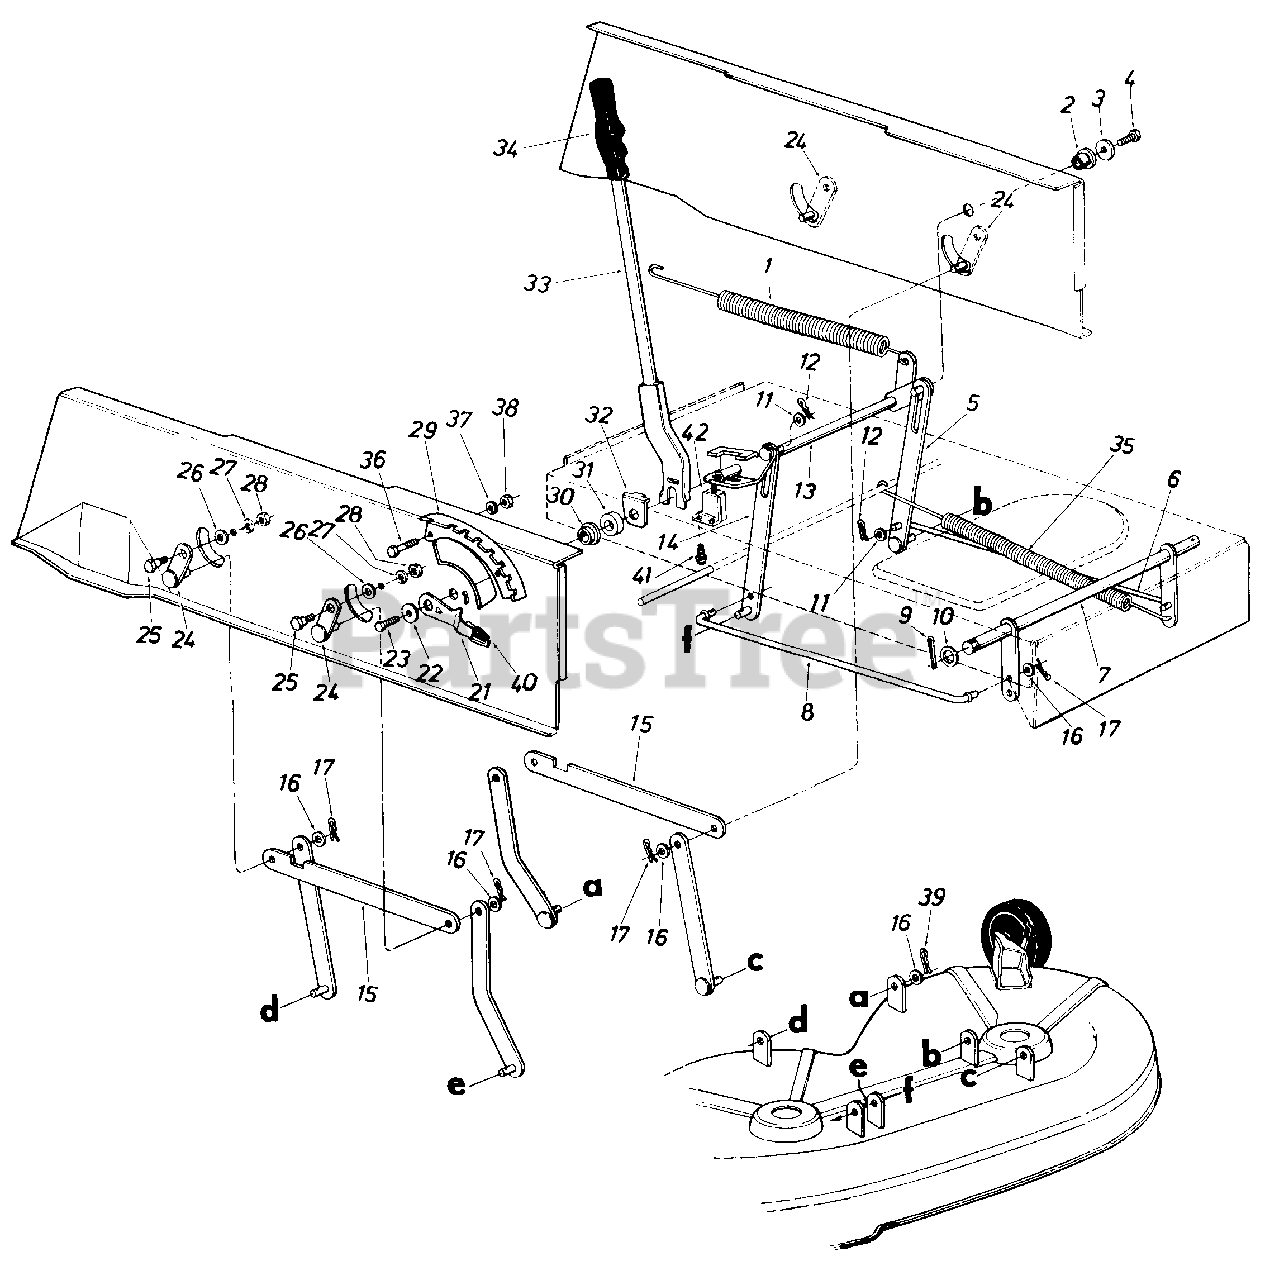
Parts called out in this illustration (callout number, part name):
1	Extension Spring .99" O.D. x 11.00" Lg.
2	Flange Bearing .634" I.D.
3	Fl-Wash. .344" I.D. x 1.125" O.D. x .125
4	Hex Wash. Hd. 5/16-18 x .62" Lg.
5	Link Deck Lift Ass'y.
6	Stabilizer Rod
7	Stabilizer Shaft Ass'y.
8	Stabilizer Rod
9	Cotter Pin 1/8" Dia. x 11/4" Lg.
10	Fl-Wash 635" I.D. x 1.12" O.D
11	Fl-Wash. .531" I.D. x .940" O.D.
12	Inter. Cotter Pin .50" Dia.
15	Connecting Rod
16	Fl-Wash. .40" I.D. x .88" O.D.
17	Inter. Cotter Pin For 3/8 Rod
21	Deck Lift Down Stop
22	Fl-Wash. .344" I.D. x 1.125" O.D. x .125
23	Hex Wash. Hd. 5/16-18 x .62" Lg.
24	Pivot Link Ass'y.
25	Shld. Bolt .437" Dia. x .180" Lg. (5/16-18)
26	Fl-Wash. .344" I.D. x .62" O.D.
27	L-Wash. 5/16" I.D.
28	Hex Nut 5/16-18 Thd.*
29	Index Brk't.
30	Flange Wash. .628" I.D. x 1.25" O.D.
31	Rubber Wash. 1.50" O.D. x .63" I.D . x .60
32	Retainer Washer Lift Handle
33	Lift Handle Ass'y.
34	Grip
35	Extension Spring .99" O.D. x 14.25" Lg.
36	Hex Bolt 5/16-18 x .75" Lg.
37	L-Wash. 5/16" I.D.
38	Hex Nut 5/16-18 Thd.
39	Inter. Cotter Pin
40	Knob
41	Hex AB-Tap Scr. #10 x .50" Lg.
42	Safety Switch
